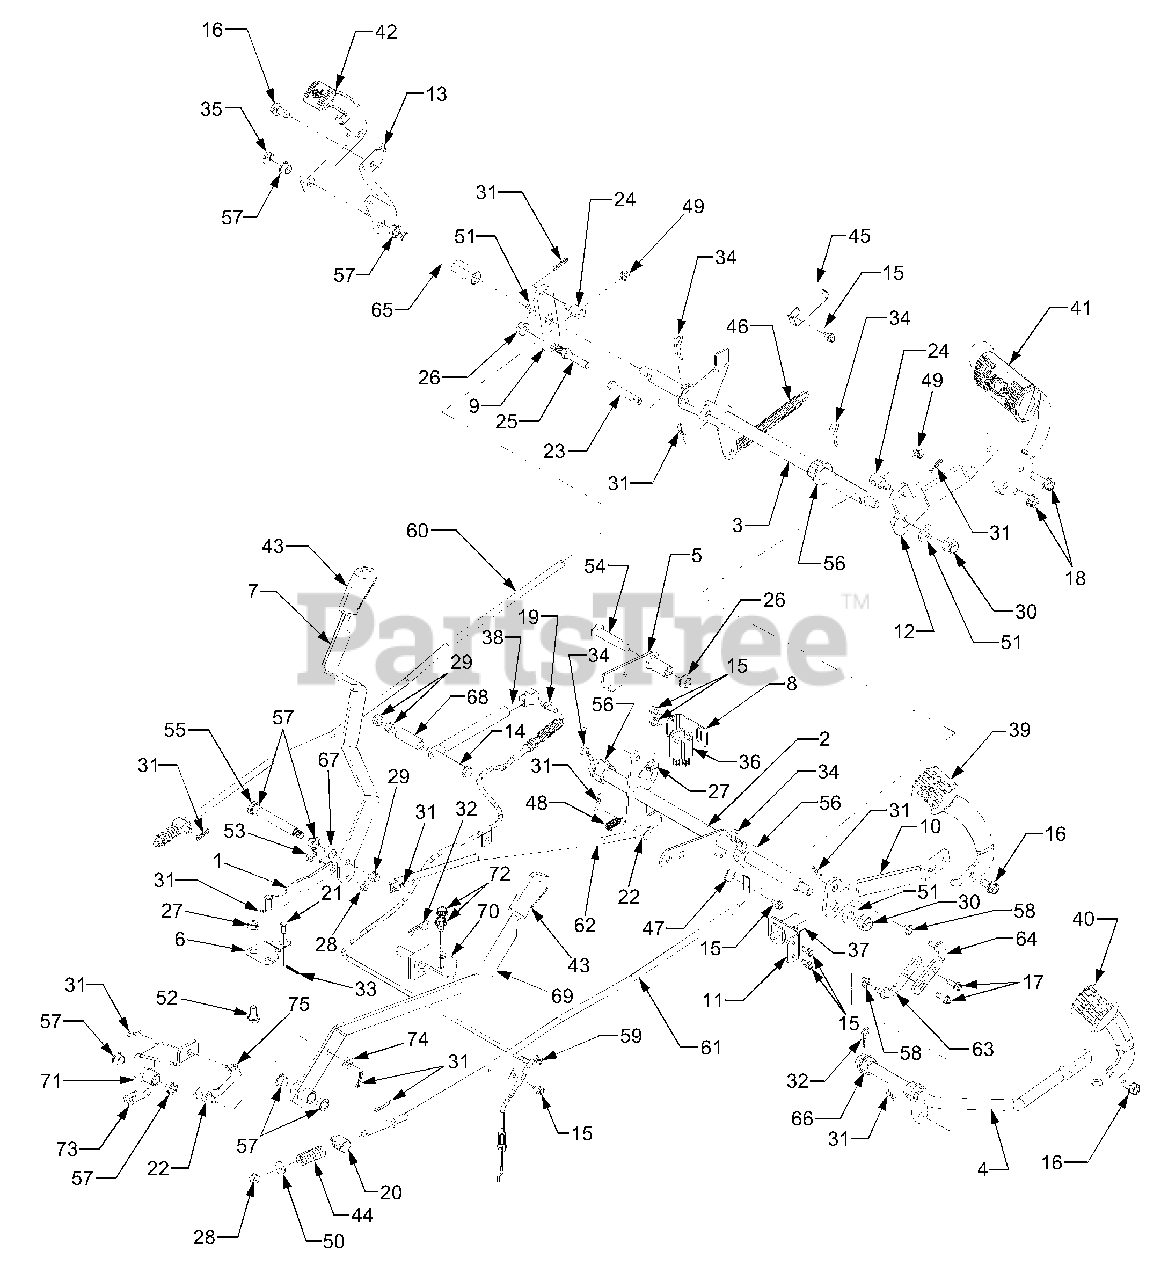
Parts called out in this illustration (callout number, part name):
1	Link, Hi-Lo
2	Shaft Assembly, Pedal
3	Shaft Assembly, Brake
4	Shaft Assembly, Reverse
5	Link Assembly, Parking Brake
6	Link, Hi-Lo Pivot
9	Lever, Brake
13	Bracket, Pedal Brace
14	Screw, Hex Cap 3/8-16 x 3.0 GR8
15	Screw, Hex Wash Hd Tapp 1/4-20 x .5
16	Screw, Hex Wash Hd Tapp 3/8-16 x .75
17	Screw, Hex Wash Hd Tapp 1/4-20 x .75
18	Screw, Hex Wash Hd Tapp 3/8-16 x 1.25
19	Stud, Cylinder, 5/16-18
20	Ferrule, Brake
21	Pin, Clevis, .25 x .5
22	Ferrule, 3/8-24 x .37
23	Pin, Clevis, 3/8 x 2.015
24	Ferrule, 3/8 - 24 x .375
25	Pin, 3/8-16: 3/8 x 2.43
26	Nut, Hex Flange Lock, 3/8-16
27	Nut, Hex Flange Lock, 5/16-18
28	Nut, Hex Flange Lock, 1/4-20
29	Nut, Hex Lock, 3/8-16
30	Nut, Hex Insert Lock, 1/2-20
31	Pin, Internal Cotter
32	Pin, Internal Cotter
33	Pin, Cotter, 3/32 x .750
34	Pin, Internal Cotter
35	E-Ring, .5 Dia
36	Switch, Plunger (Reverse)
37	Switch, Plunger (Brake)
38	Cylinder, Damper
39	Pedal, Forward
40	Pedal, Reverse
41	Pedal, Brake
42	Pedal, Diff. Lock
43	Grip, Handle
44	Spring, Compression
45	Spring, Switch Actuator
46	Spring, Extension, .62 x 6.12
47	Spring, Rev/No Cut
48	Spring, Extension, 3/8 x 1.44
49	Nut, Hex Jam, 3/8-24
50	Washer, Flat, .28 x .74 x .063
51	Washer, Flat, .53 x .1.06 x .134
52	Screw, Shoulder, .435 x 1.78
53	Screw, Shoulder, .375 x .181
54	Screw, Shoulder, .498 x 1.635
55	Screw, Shoulder .498 x 3.245: 3/8-16
56	Bearing, Hex Flange, .752 ID
57	Bearing, Nylon. .50 ID x .341
58	Bearing, Flange, .375 x .58 x .25
59	Cable, Diff Lock
60	Rod, Brake, LH
61	Rod, Brake, RH
62	Rod, Hydro Control
63	Rod, Rear Connecting
64	Rod, Front Connecting
65	Shaft, Diff. Lock
66	Bearing, Hex Flange, .629 ID
67	Spacer, .50 ID x .62 x .37
68	Spacer, .39 x .625 x 1.74
69	Handle, 4WD
70	Bracket, 4WD Pivot
72	Screw, Hex Wash. Hd. Tapp, 5/16-18 x .5
73	Link, Chain
74	Washer, Flat, .375 x .74 x .063
75	Link, 4WD Handle
